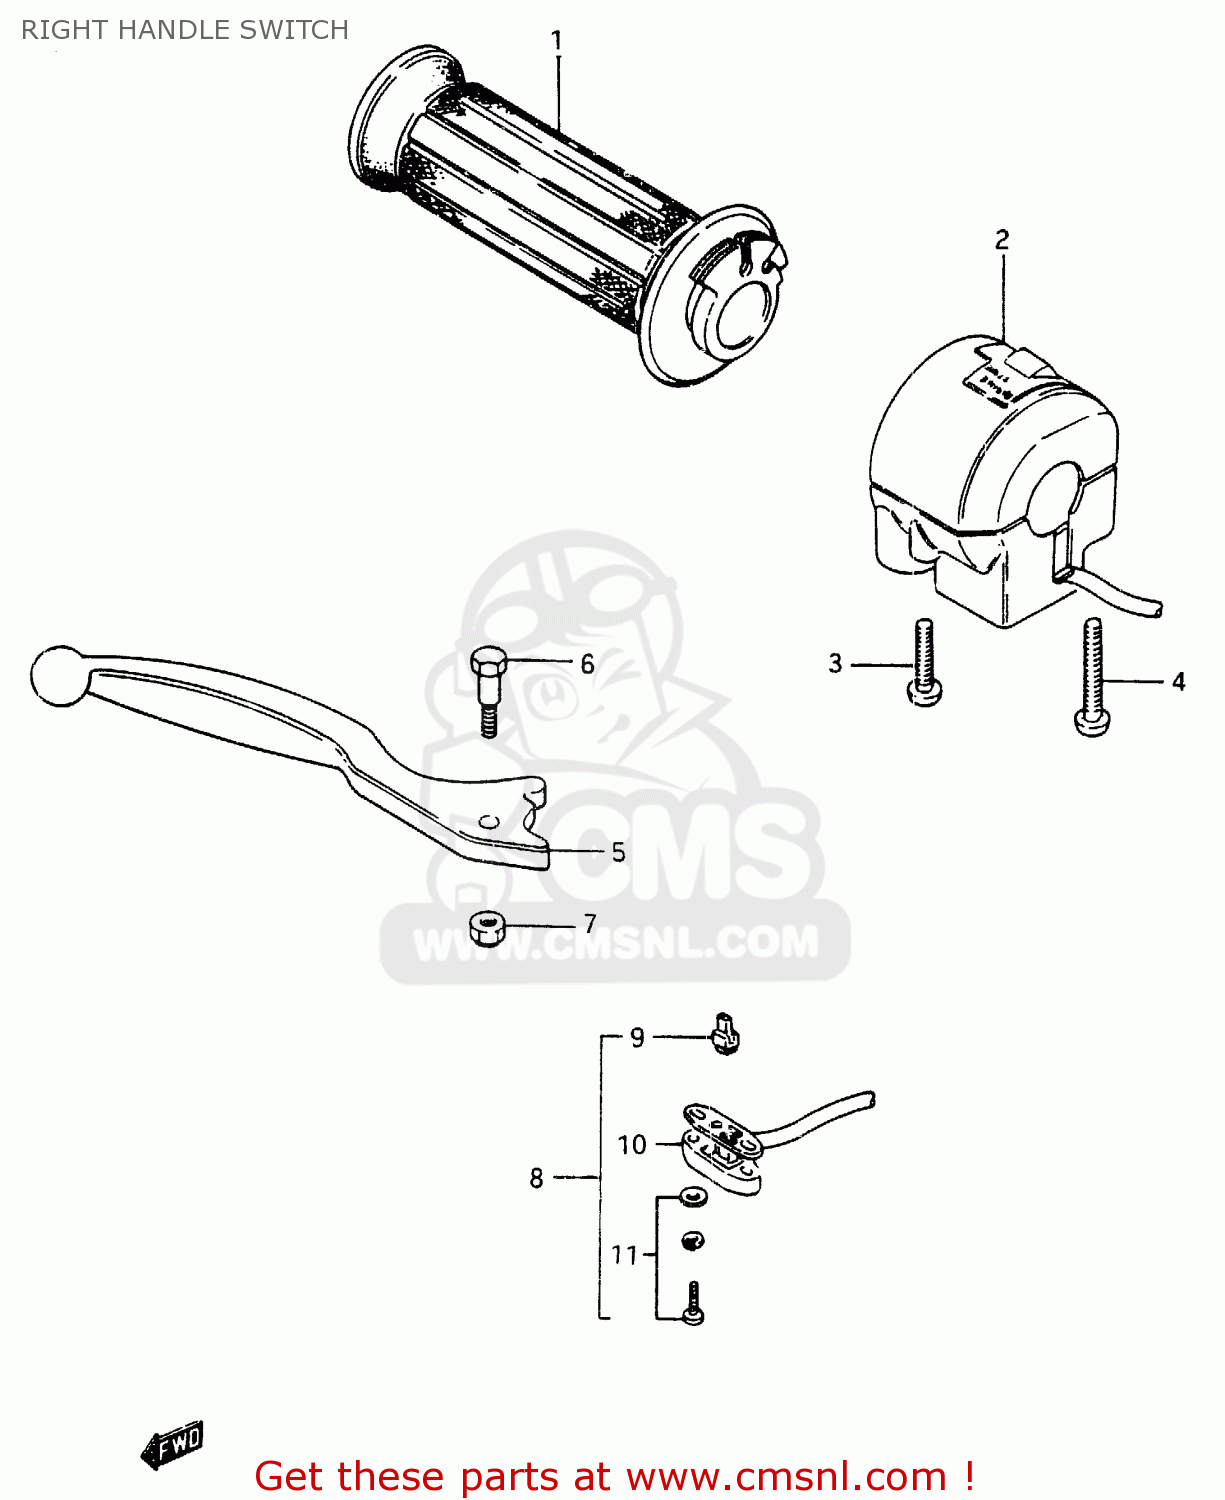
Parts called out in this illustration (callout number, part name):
1	GRIP,THROTTLE
2	SWITCH ASSY, HANDLE
3	SCREW
4	SCREW
5	LEVER,BRAKE
6	BOLT,LEVER PIVOT
7	NUT
8	SWITCH ASSEMBLY
9	CONTACT,SWITCH
10	COVER,FR BK TERMINAL BASE
11	SCREW
